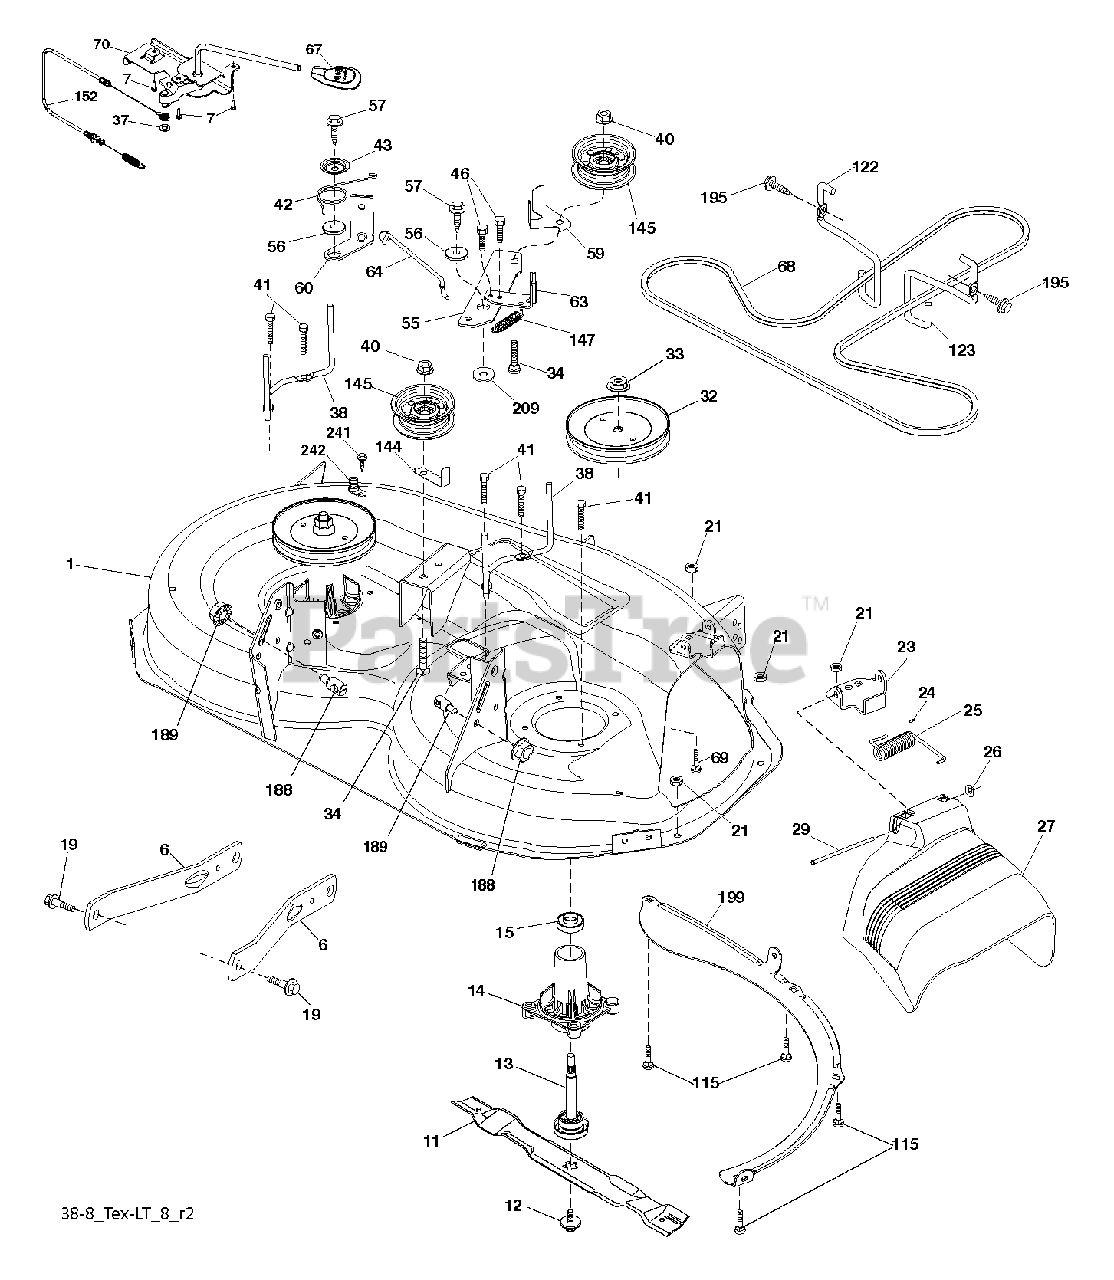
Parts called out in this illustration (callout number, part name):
1	DECK.38.WELDMENT.GREY
6	ARM.SUSPENSION.MOWER.R
7	SCREW.#10 X 0.750.BOS
11	BLADE.2 IN 1.38"DECK
12	SCREW.SEMS.7/16-20X1.HEX.HEAD
13	SHAFT ASM.MNDRL.N/GREASEABLE
14	HOUSING.MANDREL.4PT.
15	BEARING.MANDREL.TOP.EXTENDED
19	BOLT.SHOULDER
21	LOCKNUT
23	BRKT.DEFLECTOR.38"2005+
24	CAP-SLEEVE LT
25	SPRING.TORSION.DEFLECT
26	NUT PUSH M
27	SHIELD, DEFLECTOR
29	ROD.HINGE
32	PULLEY.MANDREL.5.0.PD.38"
33	NUT.FLANGE.LOCK.TOP
34	BOLT.3/8-16X1.50
37	WASHER
38	KEEPER BELT LH MANDREL
40	NUT LOCK FLG 3/8-16 UNC
41	BOLT.HEX.WASHR.HED.313-18X1.19
42	SPRING.TORSION.BRAKE
43	SRPING.TORSION.RETAINE
46	SCREW.1/4-20X5/8
56	SPACER.RETAINER
57	SCREW 3/8-16X1
59	GUARD, BELT
60	ARM BRAKE MOWER RH 38"
63	RP ARM.BRAKE.MOWER.38"LH.TEX
64	LINK BRAKE
67	HANDLE.CLUTCH.CABLE.LT
69	BOLT
70	CLUTCH.ASM.MANUAL.LT.PRED
115	BOLT
122	KEEPER BELT ENGINE LH
123	KEEPER BELT RH
144	KEEPER BELT
145	PULLEY.IDLER.48"PRIMARY
147	SPRING RETURN
152	CABLE.CLUTCH.MANUAL.
188	STUD.FASTNER.W/ANTI-ROTATE
189	NUT LOCK HEX FLANGE 5/16-18
195	SCREW, 3/8-16X3/4
199	BAFFLE.VORTEX.FRONT.38"
209	WASHER 12/32X2X10GA
241	SCREW.TT.#10-32X.5.3/8.FLANGE
242	PORT.WASHOUT
